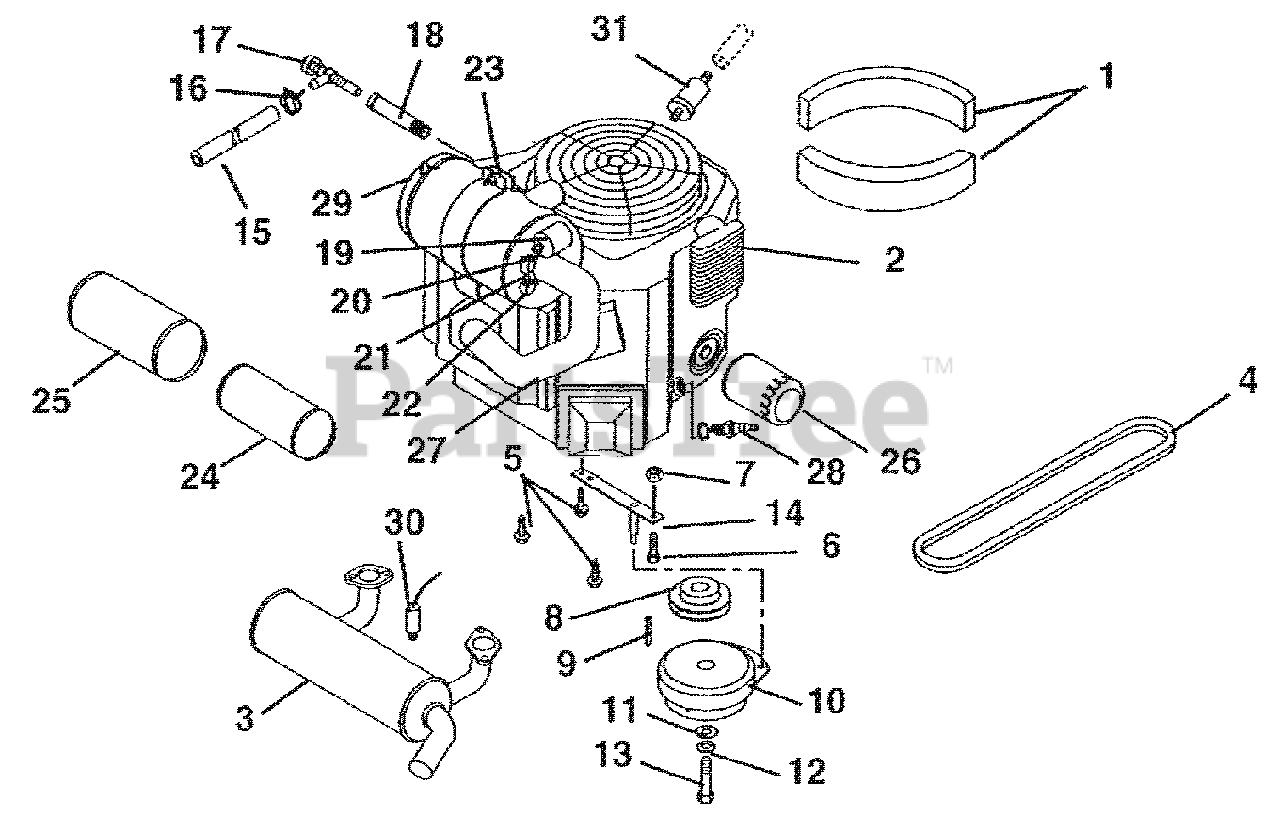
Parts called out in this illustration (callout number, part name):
1	Seal, Foam
2	Engine, Kohler 28HP EFI (069)
3	Muffler, Kohler EFI (069)
4	Belt, Poly0V
5	Screw, Tapping Hex Washer Head .38-16 x 1.00
6	Bolt, Hex .31-18 x 1.75 Grade 5
7	Nut, Locking Top Flange .31-18
8	Sheave, Poly V 1.127 x 3.25
9	Key, Square .25 x 1.00 x .25
10	Clutch, Electric
11	Washer, Flat Steel .515 x 1.625 x .250
12	Washer, Locking .44 x .109
13	Bolt, Hex .44-20 x 3.00 Grade 5
14	Anchor, Clutch
15	Gas Line, Bulk .25 ID (066, 067, 068, 070, 071, 072)
16	Hose, Clamp
17	Cock, Oil Drain
18	Adapter, Oil drain
19	Filter Minder (068, 069, 071, 072)
20	Nipple, .125 NPT (068, 069, 071, 072)
21	Elbow, 45 Degree .125 NPT (068, 069, 071, 072)
22	Elbow, Adapter 90 Degree, Brass, .125 x .125 (069, 069, 071, 072)
23	Bracket, Air Cleaner Mount
24	Element, Inner Safety
25	Element, Outer Primary
26	Oil Filter (068, 069, 071, 072)
27	Hose, Air Intake (068, 069, 071, 072)
28	Spark Plug (068, 069, 071, 072)
29	Assembly, Air Cleaner
30	Sensor, Oxygen (069)
31	Fuel Filter (066, 067, 070)
